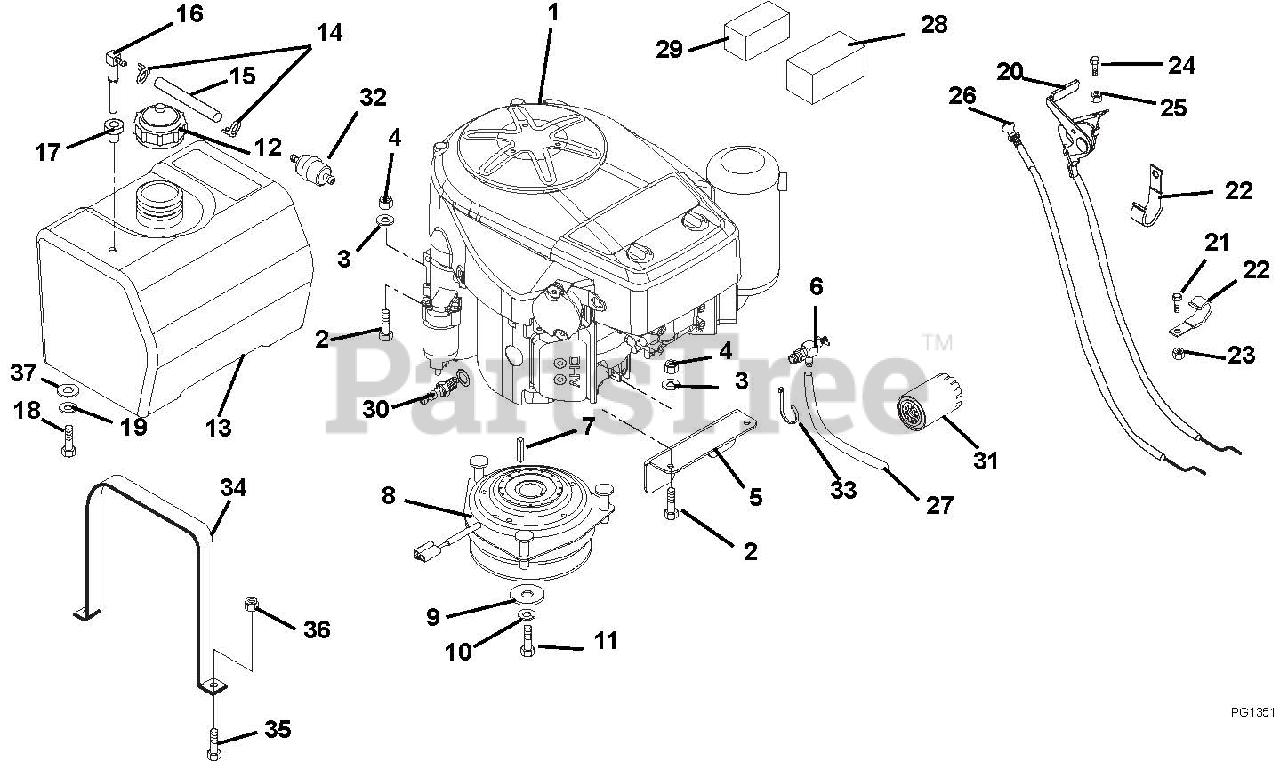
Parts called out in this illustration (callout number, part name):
1	Engine, 15 HP Kawasaki FH430V - AS02
1	Engine, 13 HP Kawasaki
2	Bolt-Hex .31-18 x 1.75 Grade 5
3	Washer-Locking .31 x .078 Regular
4	Nut-Hex .31-18
5	Bracket, Clutch
6	Valve, Oil Drain
7	Key-Square .25 x 1.25 x 25 SAE 8630 OR SAE 1035
7	Key-Square .25 x 1.00 x .25 SAE 8630
8	Clutch, Electric
9	Washer-Flat-Steel .469 x 2.00 x .25
10	Washer-Locking .44 x .109 Regular
11	Bolt-Hex .44-20 x 3.00 Grade 5
11	Bolt-Hex .44-20 x 2.50 Grade 5
12	Cap, Fuel
13	Tank, Fuel
14	Clamp-Hose Wire .49/.51 x .116
15	Gas Line-Bulk .25 I.D.
16	Fitting, Tank
17	Bushing
17	Grommet
18	Bolt-Hex .38-16 x .75 Grade 5
19	Washer-Locking .38 x .094 Regular
20	Cable, Throttle-with Liner
20	Cable- Throttle-with Liner
21	Bolt-Hex .31-18 x .75 Grade 5
23	Nut-Locking-Nylon .312-18
24	Screw-Machine 10-24 x .75 Hex Washer Head
25	Nut-Locking-Nylon 10-24 with Insert
26	Control, Choke
27	Tube, Oil Drain
28	Filter, Air Paper
29	Filter, Air Foam
30	Spark Plug
31	Filter, Oil
32	Fuel Filter- Kawasaki
33	Cable Tie
34	Tank Strap
35	Bolt, Round Head Square Neck .25-20 x .75 Grade 5
36	Nut, Locking Nylon .25-20
37	Washer, Flat Steel .409 x .812 x .065
